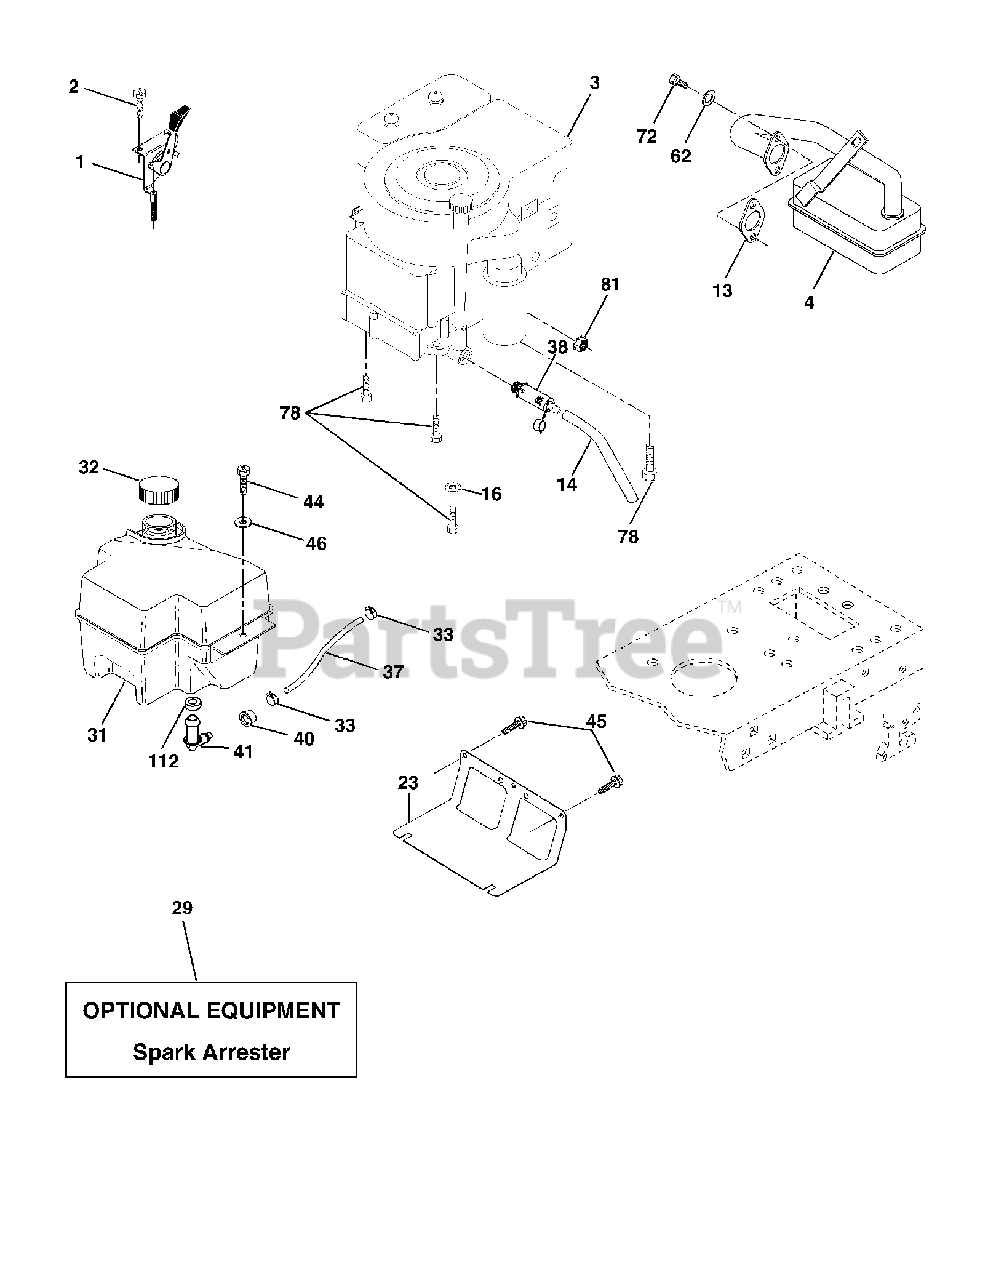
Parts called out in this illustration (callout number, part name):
1	CONTROL.THROTTLE/CHOKE.BLACK
4	MUFFLER.LT.BRIGGS.14HP.IC/OHV
14	TUBE, DRAIN OIL ASM.
16	LOCKWASHER
23	SHIELD.BROWNING.DBR.GUARD
29	KIT.SPARK ARRESTOR(392390 B&S)
31	GAS TANK 2GAL
33	HOSE CLAMP
37	LINE.FUEL.20
40	GROMMET T
41	STEM FUEL TANK
44	SCREW HEXWSHR 1/4-20X3/4
45	SCREW, 3/8-16X3/4
62	LOCKWASHER
72	Socket Head Screw, 5/16-1
78	SCREW.3/8-16
81	NUT
112	Outlet T-Bushing
